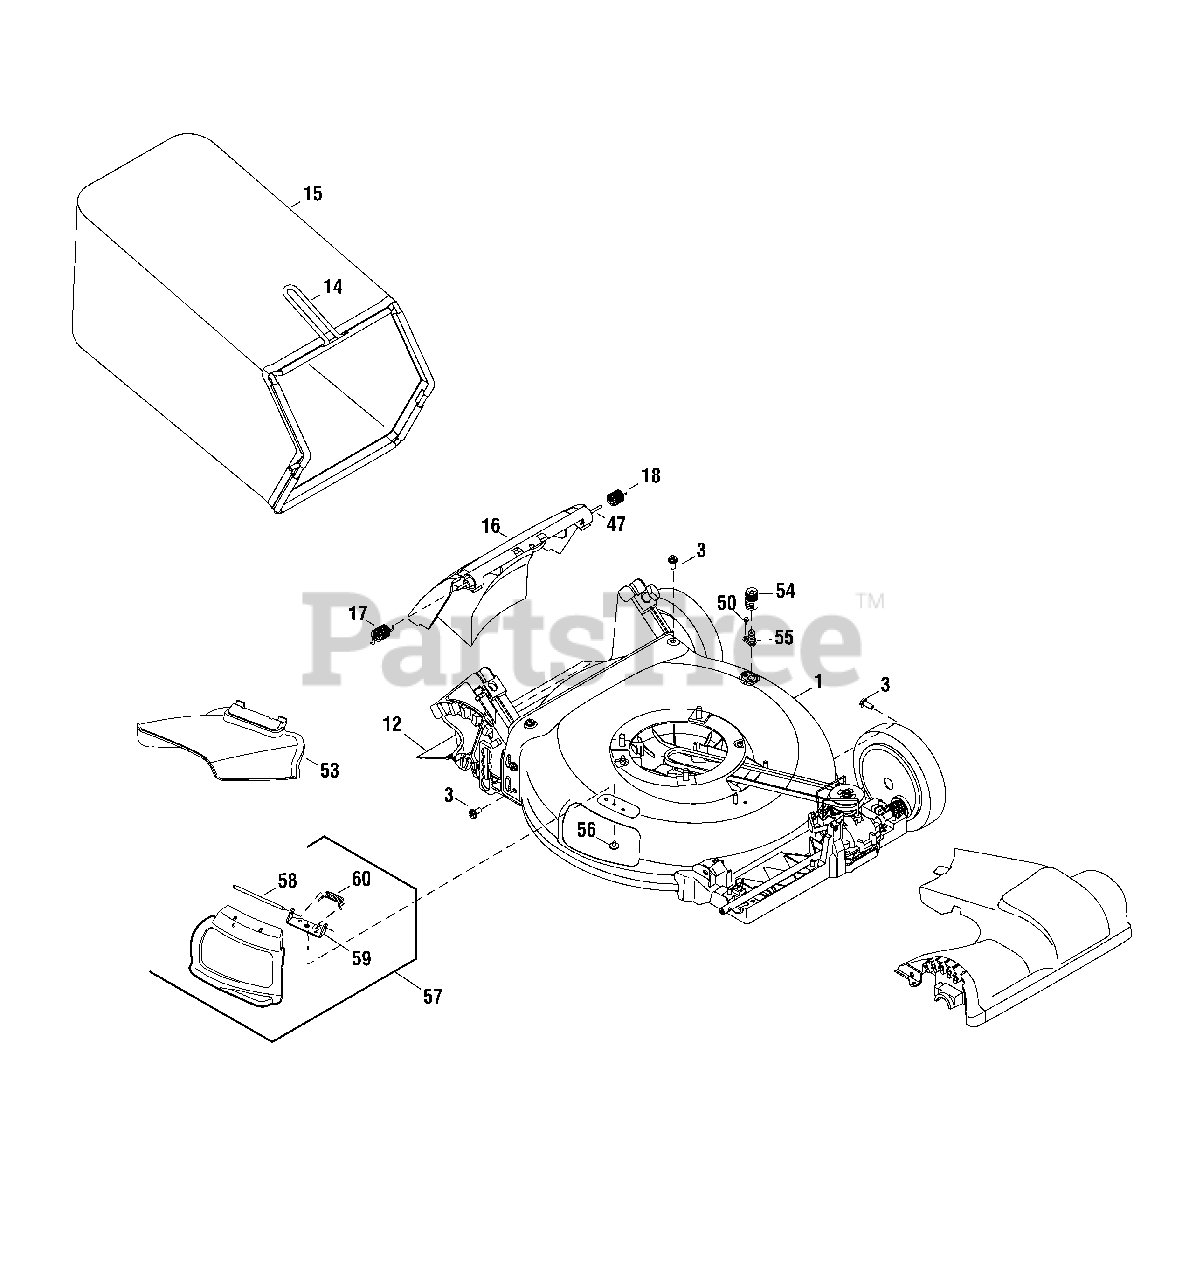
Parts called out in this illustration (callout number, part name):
3	SCREW, 5/16-14 x 3/4
12	SHIELD, Trailing
14	FRAME, Grass Bag
15	BAG, Grass
16	DOOR, Rear Discharge
17	SPRING, Torsion, RH
18	SPRING, Torsion, LH
47	ROD, Pivot
50	BOLT, Shoulder, 1/4-20 x 1/2
53	CHUTE, Side Discharge
54	ADAPTER, Water Nozzle
55	NOZZLE, Water
56	SCREW, 1/4-20 x 1/2
57	MULCH PLUG
58	PIN, Hinge
59	BRACKET, Chute Deflector
60	SPRING, Torsion
